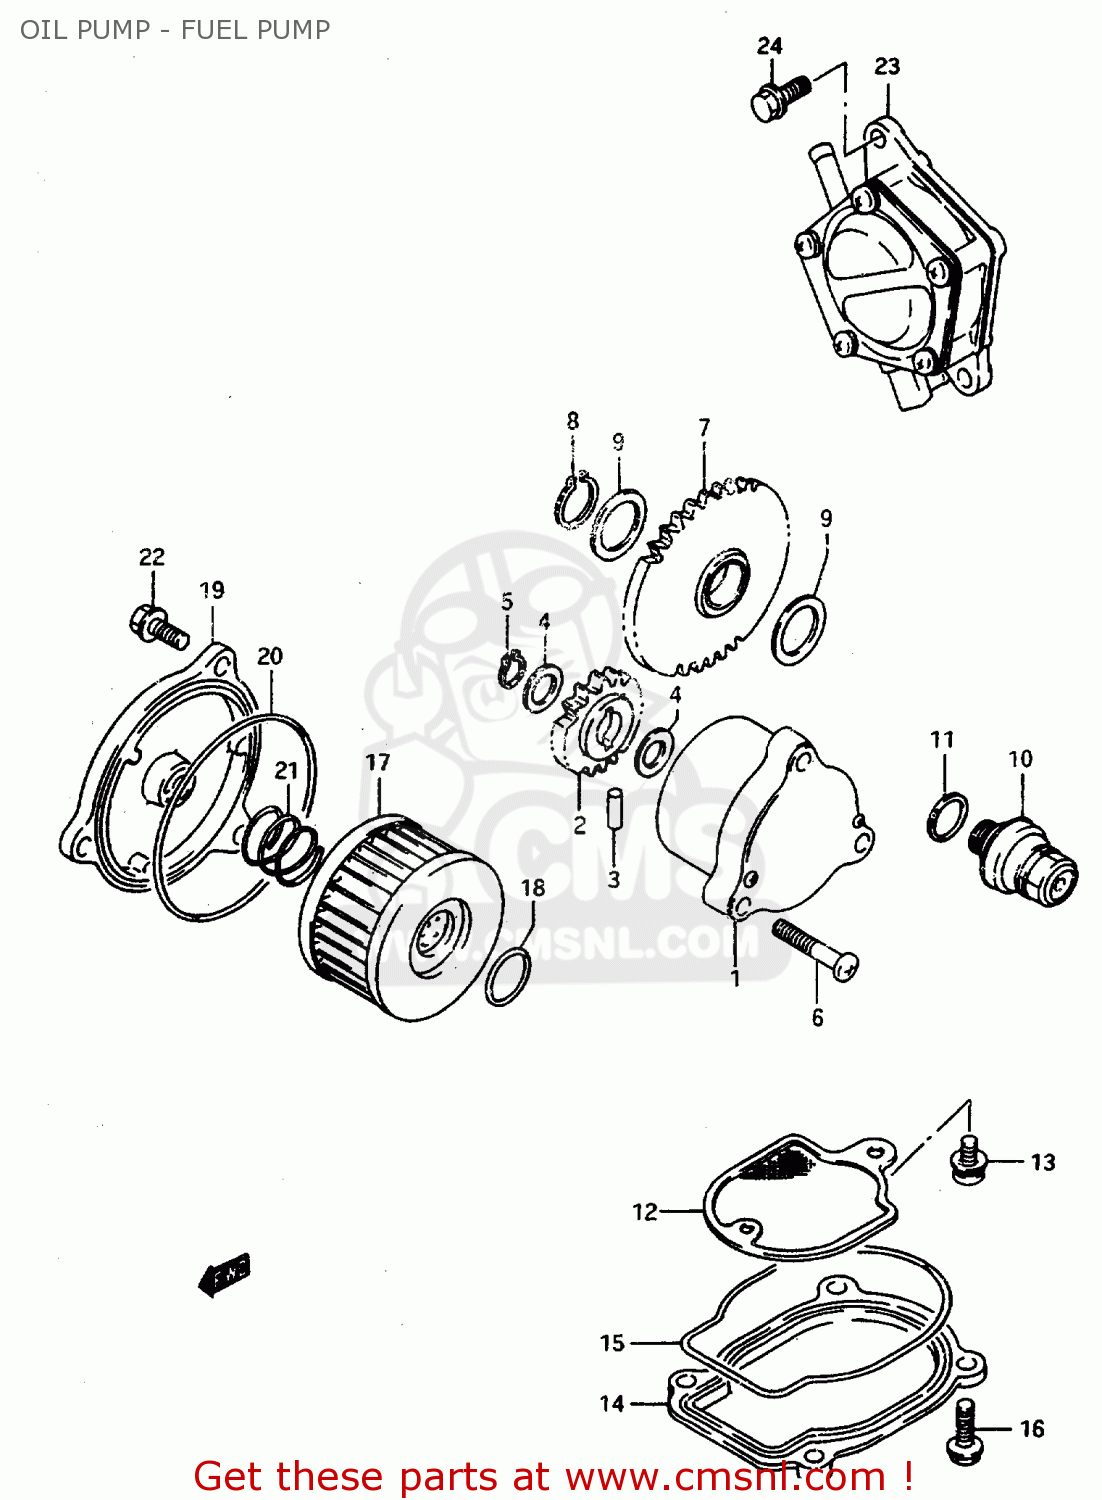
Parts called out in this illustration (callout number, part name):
1	PUMP ASSY,ENGINE OIL
2	GEAR,OIL PUMP DRIVEN(NT:15)
3	PIN(4X15.8)
4	SHIM
5	CIRCLIP,10MM
6	SCREW 6X30
7	GEAR,OIL PUMP DRIVE
8	CIRCLIP
9	WASHER
10	VALVE ASSY, OIL RELIEF
11	WASHER
12	STRAINER,ENGINE OIL
13	SCREW
14	CAP,OIL STRAINER
15	O RING,OIL STRAINER CAP
16	BOLT
17	FILTER,ENGINE OIL
18	O RING(D:2.4,ID:15.8)
19	CAP,OIL FILTER
20	O RING(D:2.4,ID:73)
21	SPRING
22	BOLT
23	PUMP ASSY,FUEL
24	BOLT
